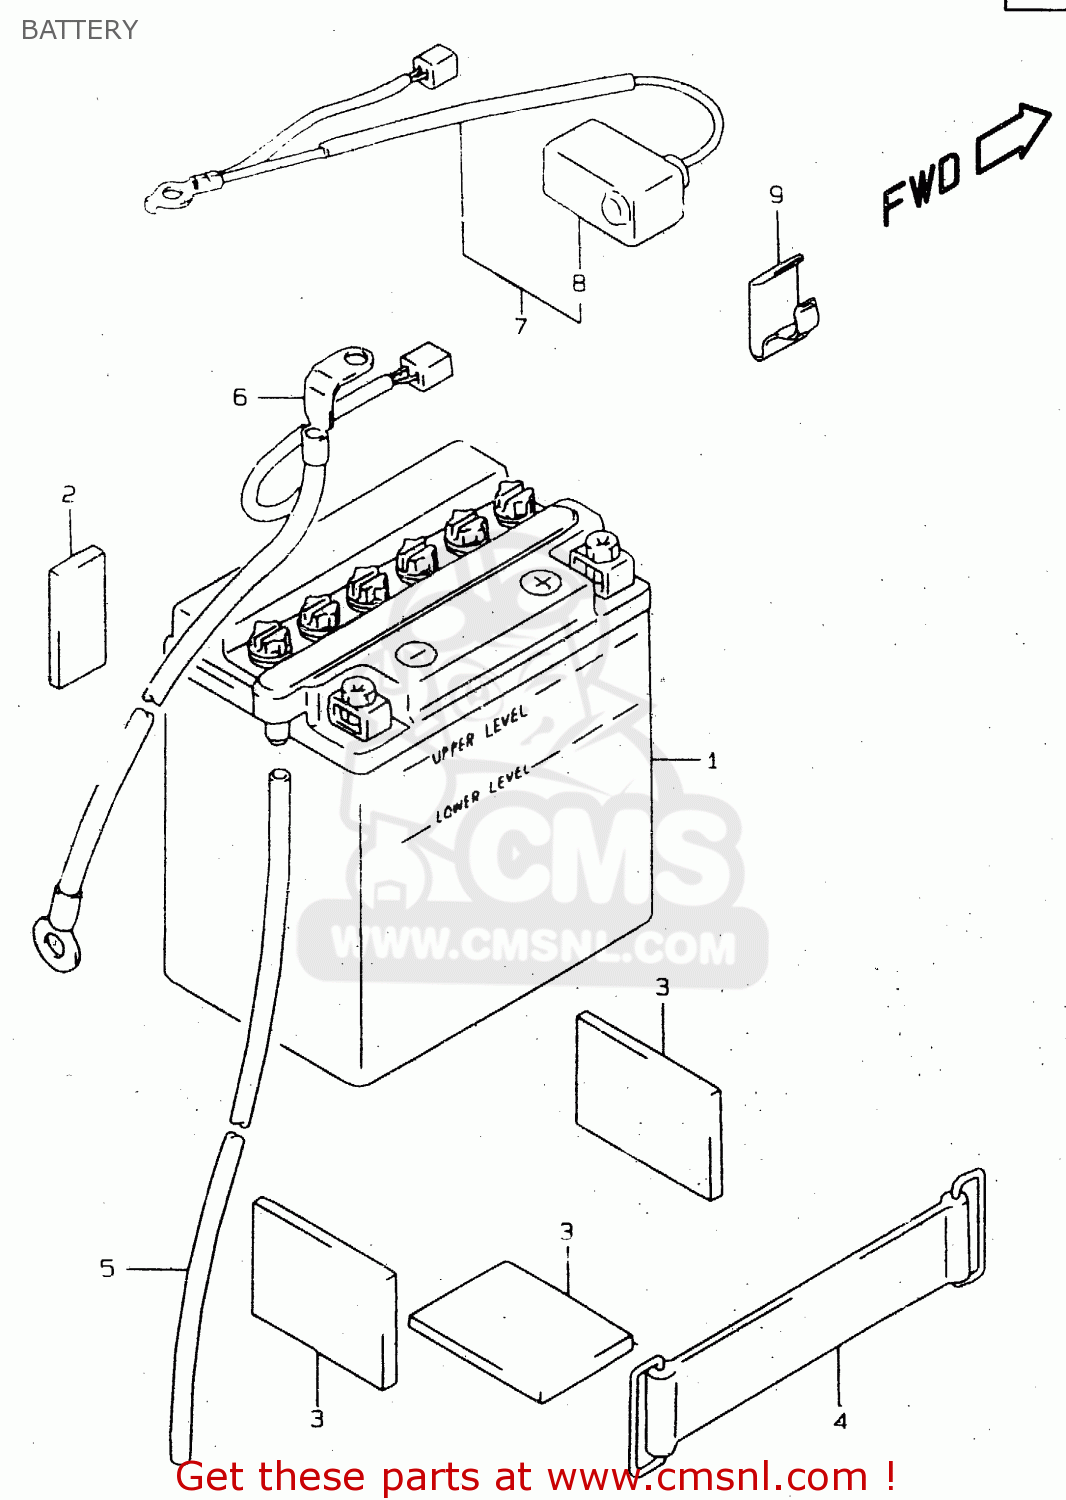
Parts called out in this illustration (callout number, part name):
1	BATTERY ASSY (12V)
2	CUSHION 20X45X6
3	PROTECTOR(170X95X3.0)
4	BAND
5	HOSE,BATTERY EXHAUST(L:780)
6	WIRE,BATTERY MINUS LEAD
7	WIRE, BATTERY (+) LEAD
8	CAP,BATTERY PLUS TERMINAL
9	HOLDER,FUSE CASE
